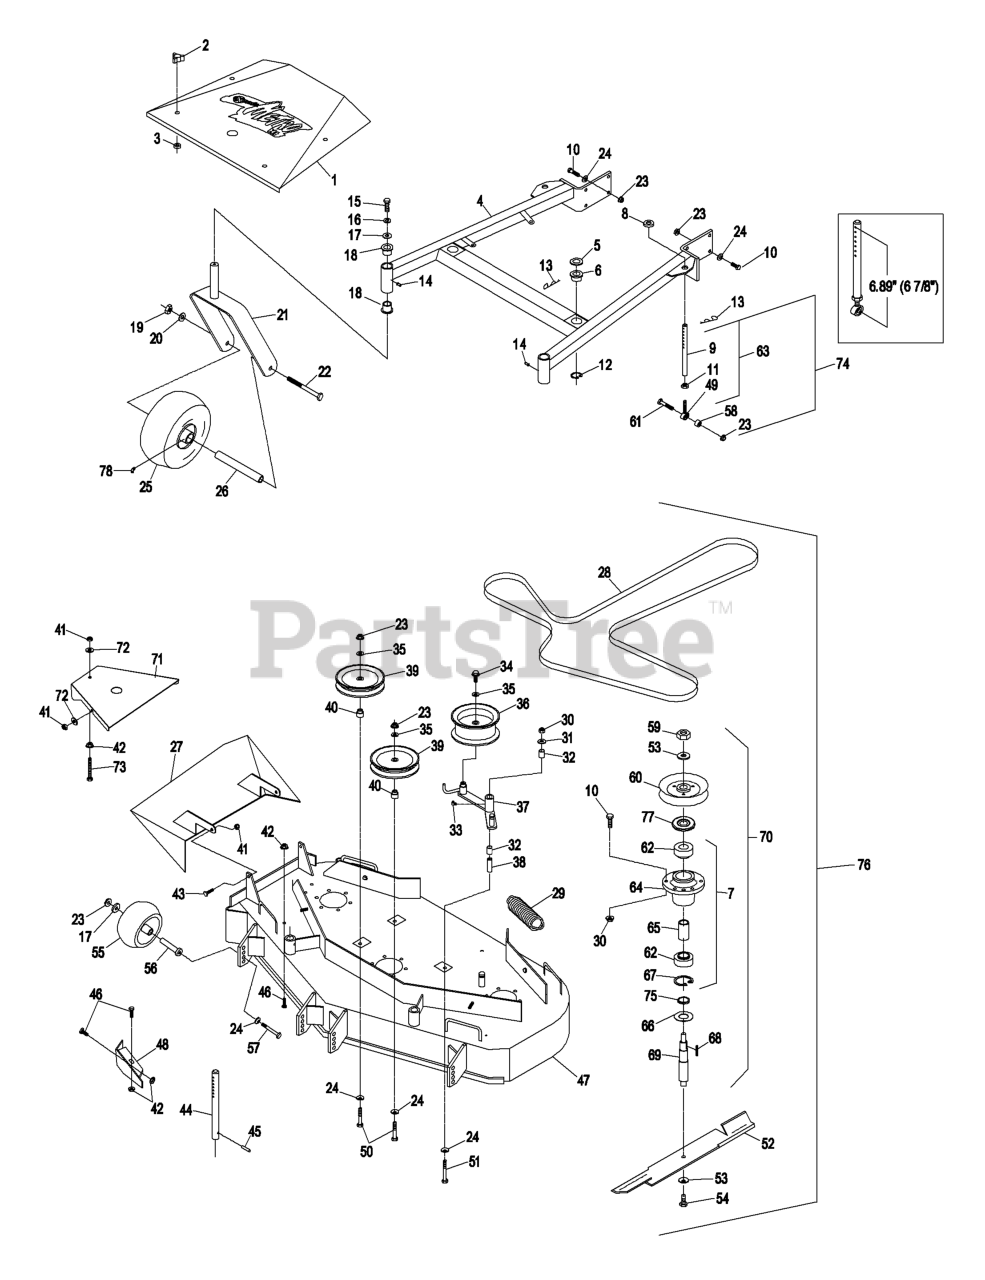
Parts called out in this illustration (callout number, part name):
2	KNOB-3 PRONG
4	DECK SUPPORT W/BSHGS 48"
5	SPACER-DECK SUPPORT
6	BUSHING-DECK
9	LINK,SUPPORT
10	SCREW-HH
11	NUT-HEX
12	RING-RETAINING
13	PIN,HAIR COTTER
14	FITTING-GREASE
15	SCREW-HH
16	WASHER-LOCK
18	BEARING-FLANGED
19	NUT-HH
20	WASHER-LOCK
22	SCREW-HH
23	NUT-HHF, WHIZ
24	WASHER-BELLEVILLE
26	SPACER FRONT CASTER
27	WLD,DISCHARGE CHUTE 36/48
28	BELT - V, B
30	NUT-LOCK, NI
31	WASHER-FLAT
32	SLEEVE-BEARING
33	FITTING-GREASE, 90 DEG
34	SCREW-HHF
35	WASHER-FLAT
38	BUSHING-PIVOT, IDLER
39	PULLEY-IDLER
40	BUSHING-IDLER
41	NUT-LOCK, NI
43	SCREW-HH
44	ROD,DECK SUPPORT
46	SCREW-HH
47	ASM,DECK W/DECALS TTHP/MH
49	BALLJOINT
50	SCREW-HH
51	SCREW-HH
53	WASHER-SPRING
54	SCREW-CAP
55	ROLLER-SCALP, ANTI
56	BUSHING-ROLLER
57	SCREW-HH
59	NUT-HEX
60	SHEAVE,W/HUB 5.72
61	SCREW-HH
62	BEARING
65	SPACER-BEARING
66	GUARD-BEARING, BOTTOM
67	RING-SNAP
68	KEY-RECTANGLE
69	SHAFT,SPINDLE
70	HOUSING,CUTTER COMPLETE
72	WASHER-FLAT
73	BOLT,TAP HH
75	SPACER-PULLEY/BEARING
76	Assembly, Cutting Deck Complete
77	GUARD-BEARING, TOP
78	FITTING-GREASE
79	KIT, SP CASTER WHEEL REPL
